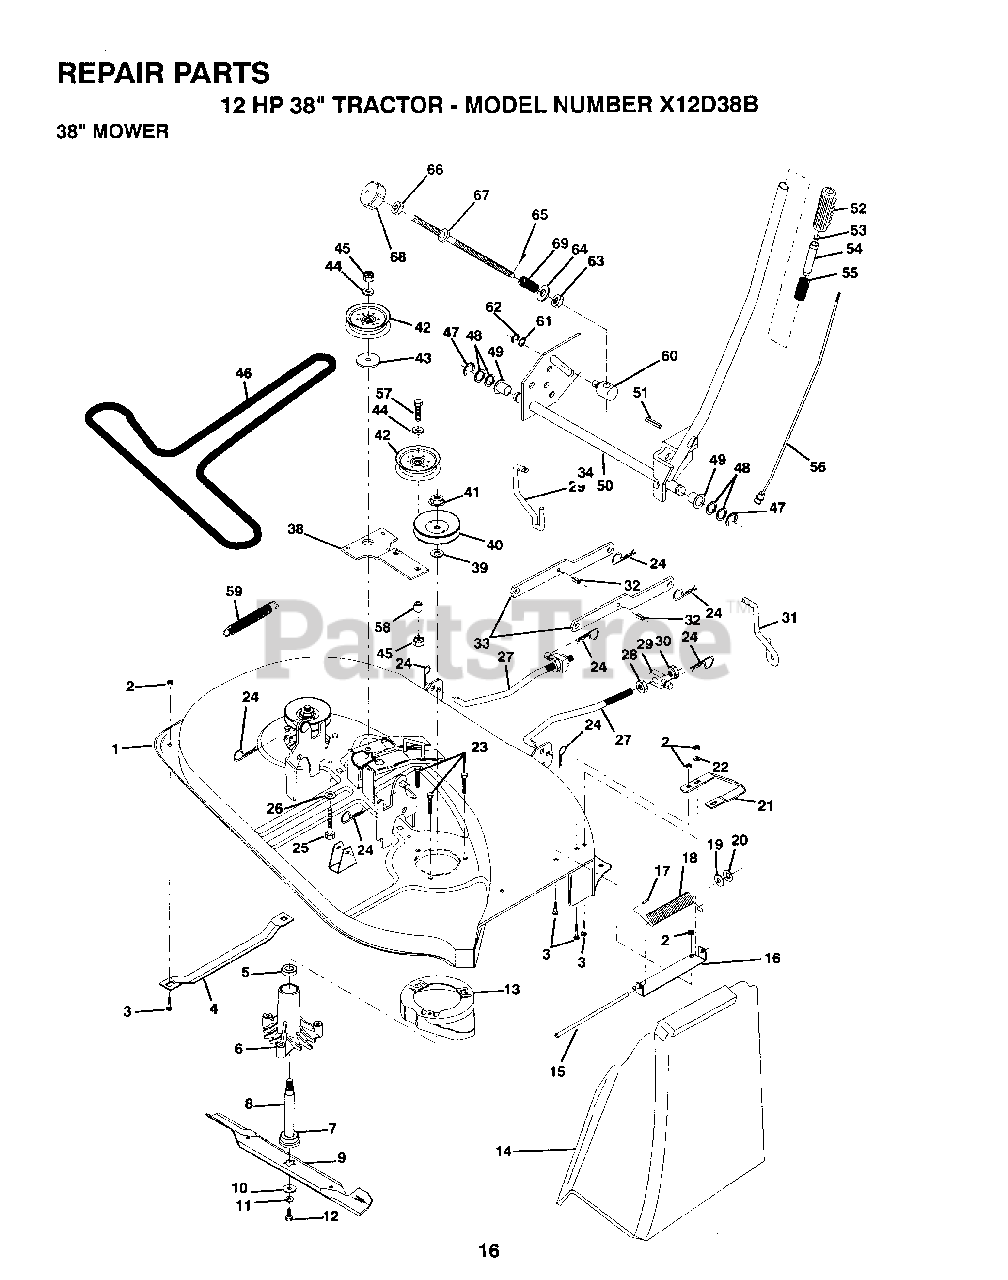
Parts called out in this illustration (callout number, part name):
3	BOLT
4	RUNNER-LH M
5	BEARING
6	HSG ASM MANDREL
7	BEARING.BALL
10	WASHER BLADE
12	BLADE BOLT
14	DEFLECTOR-SHLD T
15	ROD-HINGE T
17	NUT PUSH M
19	WASHER
20	CAP-SLEEVE LT
21	RUNNER RH
22	WASHER M
25	BOLT
26	WASHER GT
27	LINK.FRONT
28	NUT
29	TRUNION
30	NUT.LK.W/WSH.1/2.
31	LIFT LINK RH
32	"PIN,SPRING"
34	LINK LIFT LH
38	IDLER ARM ASSY
39	WASHER
42	FLAT IDLER PULLEY
43	SPACER RETAINER
44	WASHER
46	BELT-V.88.12.MW
48	WASHER
49	NYLON BEARING
51	PIN-GROOVE LT
52	GRIP
57	BOLT
59	SPRING.EXTENSION
60	TRUNION LT
61	WASHER
62	KLIP RING
63	NUT T
64	WASHER
66	NUT
69	SPRING T
